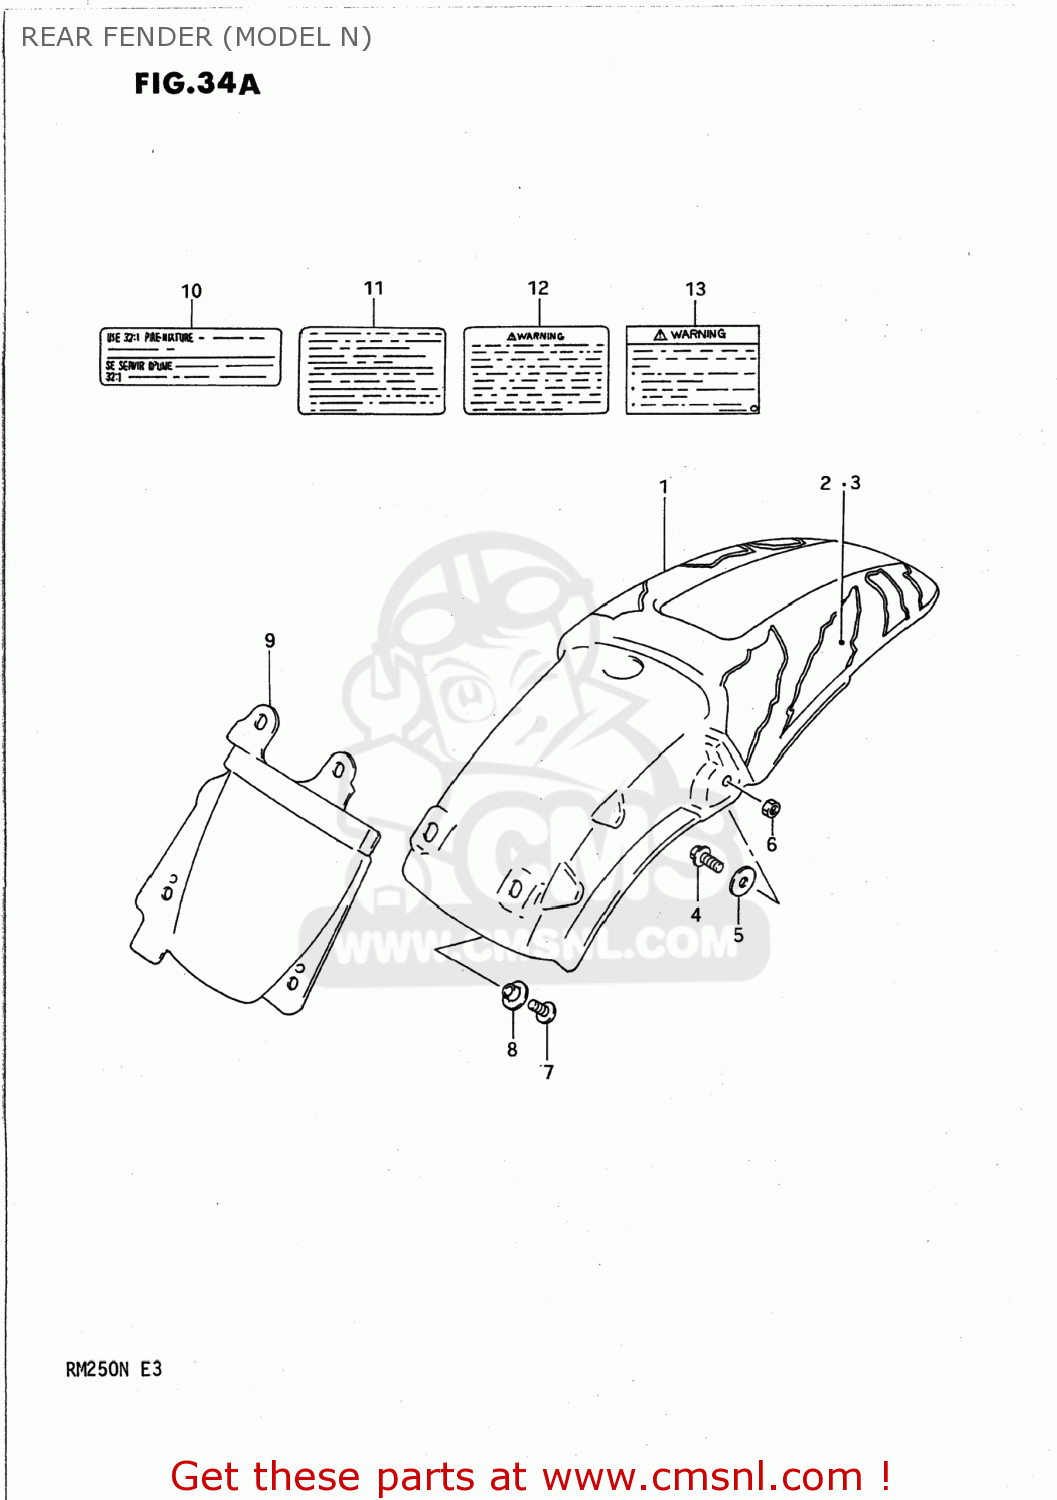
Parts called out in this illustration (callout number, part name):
1	BODY,RR FENDER
2	EMBLEM,REAR FENDER,RIGHT
3	EMBLEM,REAR FENDER,LEFT
4	BOLT
5	WASHER (6.5X29X1.6)
6	NUT 6MM
7	SCREW
8	WASHER
9	MUD GUARD,REAR FENDER,FRONT
10	LABEL,WARNING NO.2
11	LABEL,WARNING
12	LABEL,WARNING
13	LABEL
